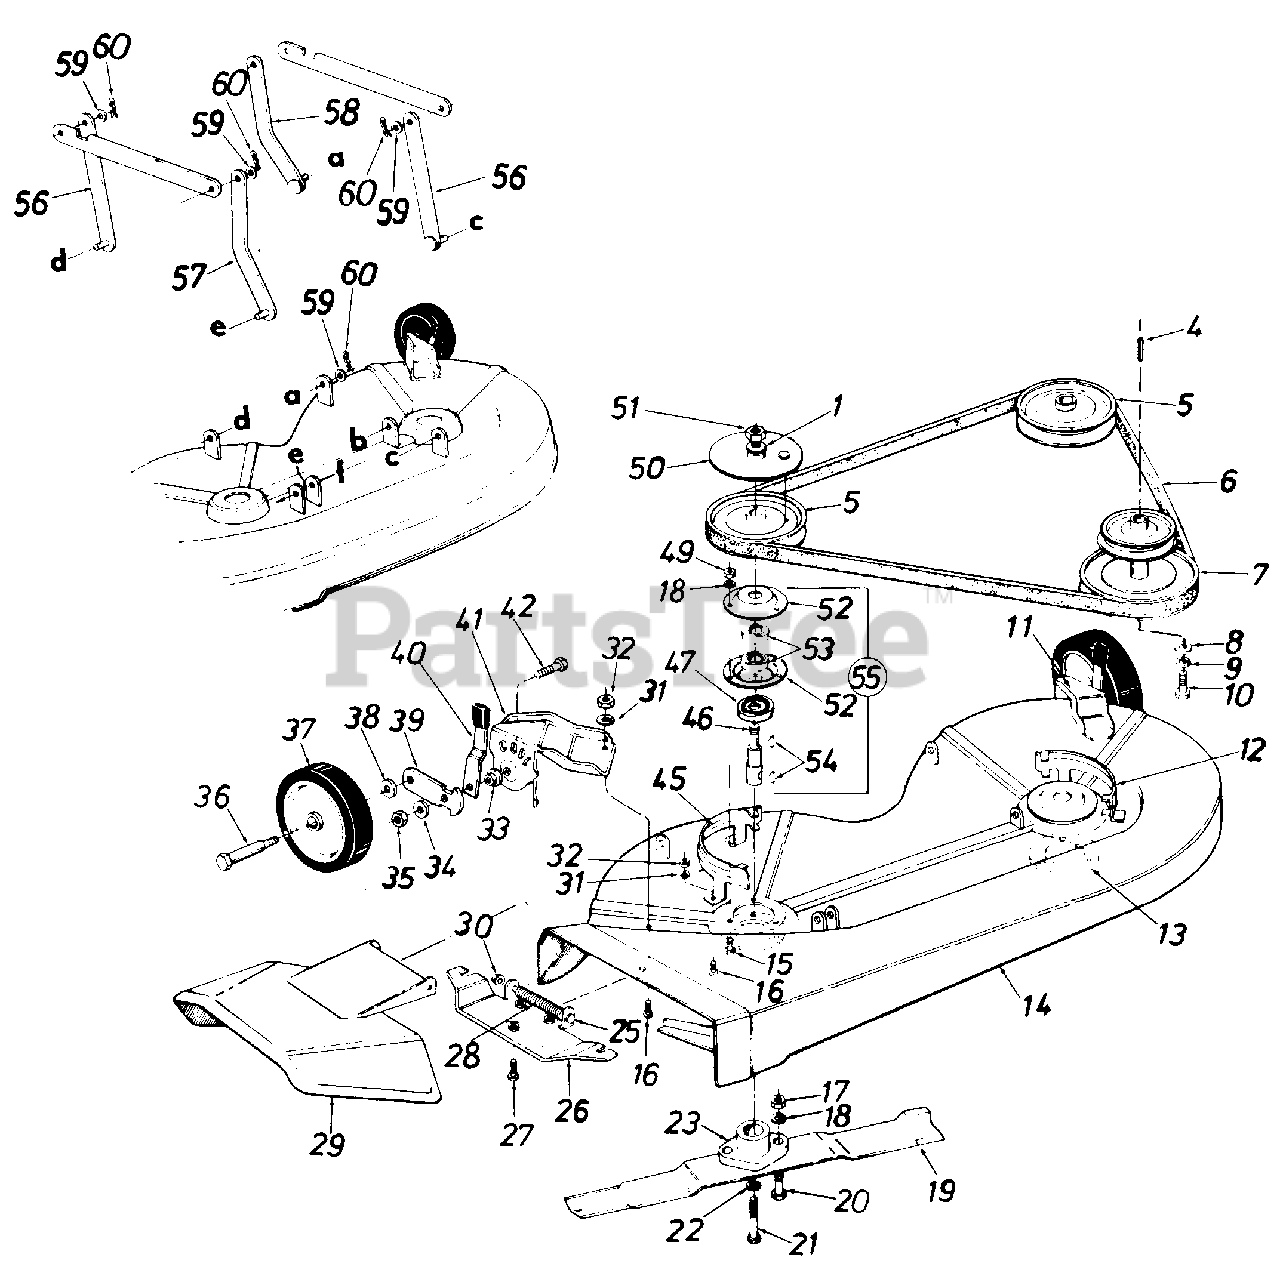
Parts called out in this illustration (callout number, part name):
1	L-Wash. 5/8" I.D.
4	Sq. Key 1/4" x 1/4" x 2.0" Lg.
5	Pulley 4.75" O.D.
6	"V"-Belt
7	See Lawn Tractor Manual
8	Fl-Wash. 7/16" I.D. x 1.25 O.D. x .180
9	L-Wash. 7/16" I.D.
10	Hex Bolt 7/16-20 x 1.50' Lg.
11	.Wheel Brkt. L.H.
14	38" Deck Ass'y.
15	Hex Sems Bolt 5/16-18 x 1.00" Lg.
16	Hex Bolt 1/4-28 x .50" Lg.
17	Hex Nut 5/16-24 Thd.
18	L-Wash. 5/16" I.D.
19	19" Blade
20	Hex Bolt 5/16-24 x 1.00" Lg. (Grade 5)
21	Hex Bolt 3/8-24 x 1.50" Lg. (Grade 5)
22	L-Wash. 3/8" I.D.
23	Blade Adapter Kit
25	Hinge Pin
26	Adapter Plate
27	Hex Wash. Self-Tap Scr. 1/4-20 x .50" Lg.
28	Torsion Spring
29	Chute Cover Ass'y. Comp.
30	Push Nut 1/4" Rod
31	L-Wash. 1/4" I.D.
32	Hex Nut 1/4-28 Thd.
33	Shld. Spacer
34	Bell-Wash. .400" I.D. x 1.13"
35	Hex Top L-Nut 3/8-16 Thd.
36	Shld. Bolt .498" Dia. x 1.53"
37	Plastic Wheel 5.0" x 1.38"
38	Bell-Wash. .400" I.D. x .88"
39	Pivot Bar
40	Spring Lever Ass'y. w/Knob
41	Wheel Brkt. R.H.
42	Hex Bolt 3/8-16 x 1.00" Lg.
45	Belt Guard R.H.
46	Blade Spindle
47	Bearing Shield
49	Hex Nut 5/16-18 Thd.
50	Brake Disc
51	Hex Jam L-Nut 5/8-11 Thd.
52	Bearing Housing
53	Ball Bearing .787" I.D. x 1.85" O.D.
54	#6 Hi-Pro Key 5/32" x 5/8" Dia.
55	Blade Spindle Ass'y.
56	Link Deck Hanger Ass'y.
57	Link Deck Hanger Ass'y.
60	Inter. Cotter Pin .50" Dia.
